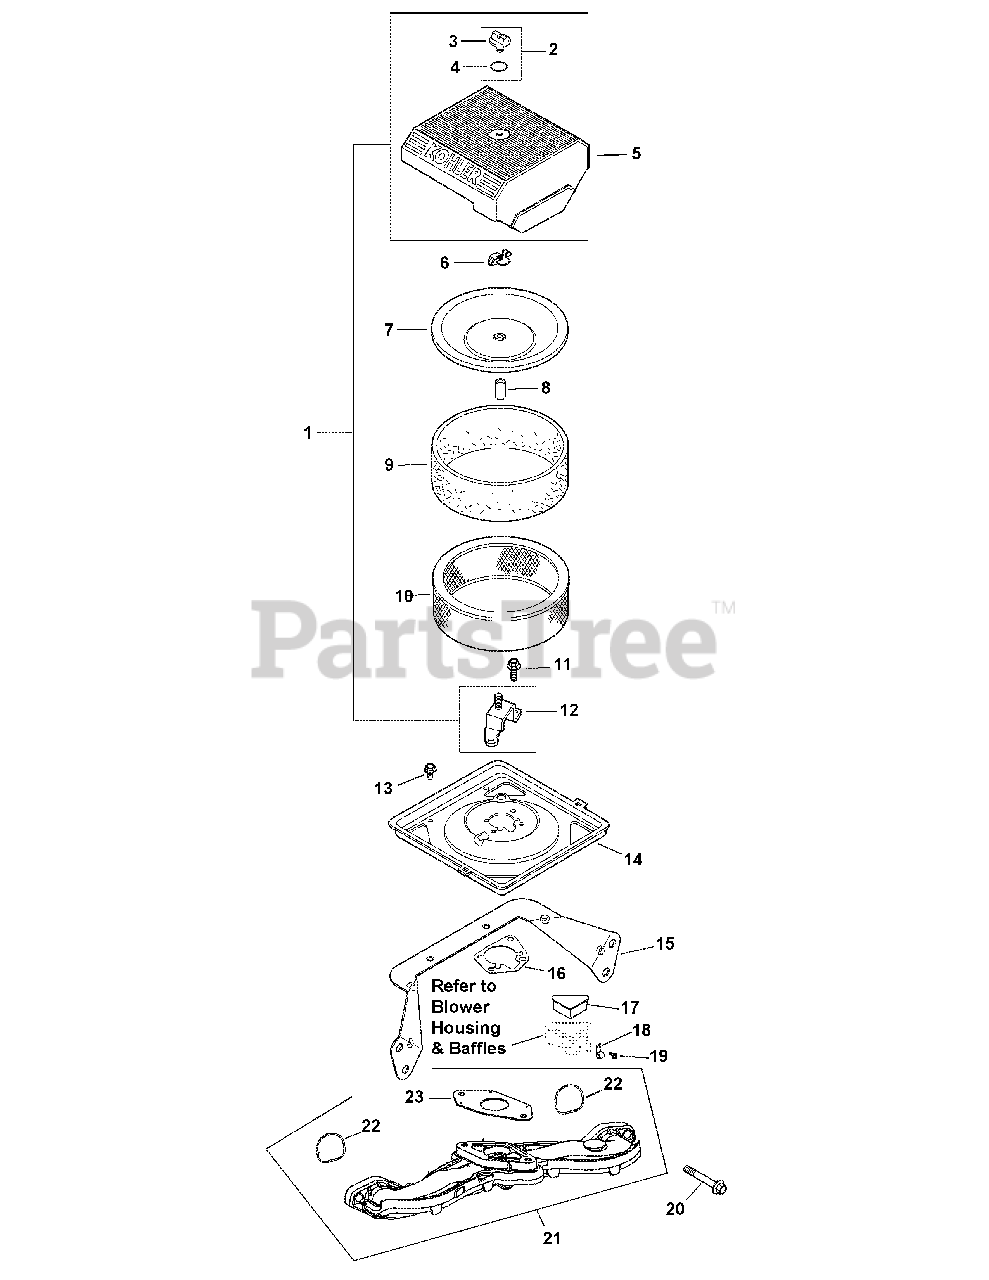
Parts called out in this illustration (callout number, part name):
1	Kit, air cleaner cover (Includes 2 5,12)
2	Kit, knob w/seal (Includes 3,4)
3	Knob, cover
4	O-Ring
5	Cover, air cleaner
7	Cover, inner air cleaner
8	Seal, inner air cleaner
9	Element, precleaner
10	Element, air cleaner
11	Screw, flg thd frm M6x1.0x16
12	Bracket, air cleaner
13	Screw, flg thd frm M5x0.8x10
14	Base, air cleaner
15	Bracket, air cleaner base
16	Gasket, air cleaner base
17	Cover, blower housing
18	Clip, cable
19	Screw, wsh hd tap #8-18x1/2"
20	Screw, flg M6x1.0x40
21	Manifold, intake - plastic (Includes 21,22)
22	O-Ring, intake port
23	Gasket, carburetor
